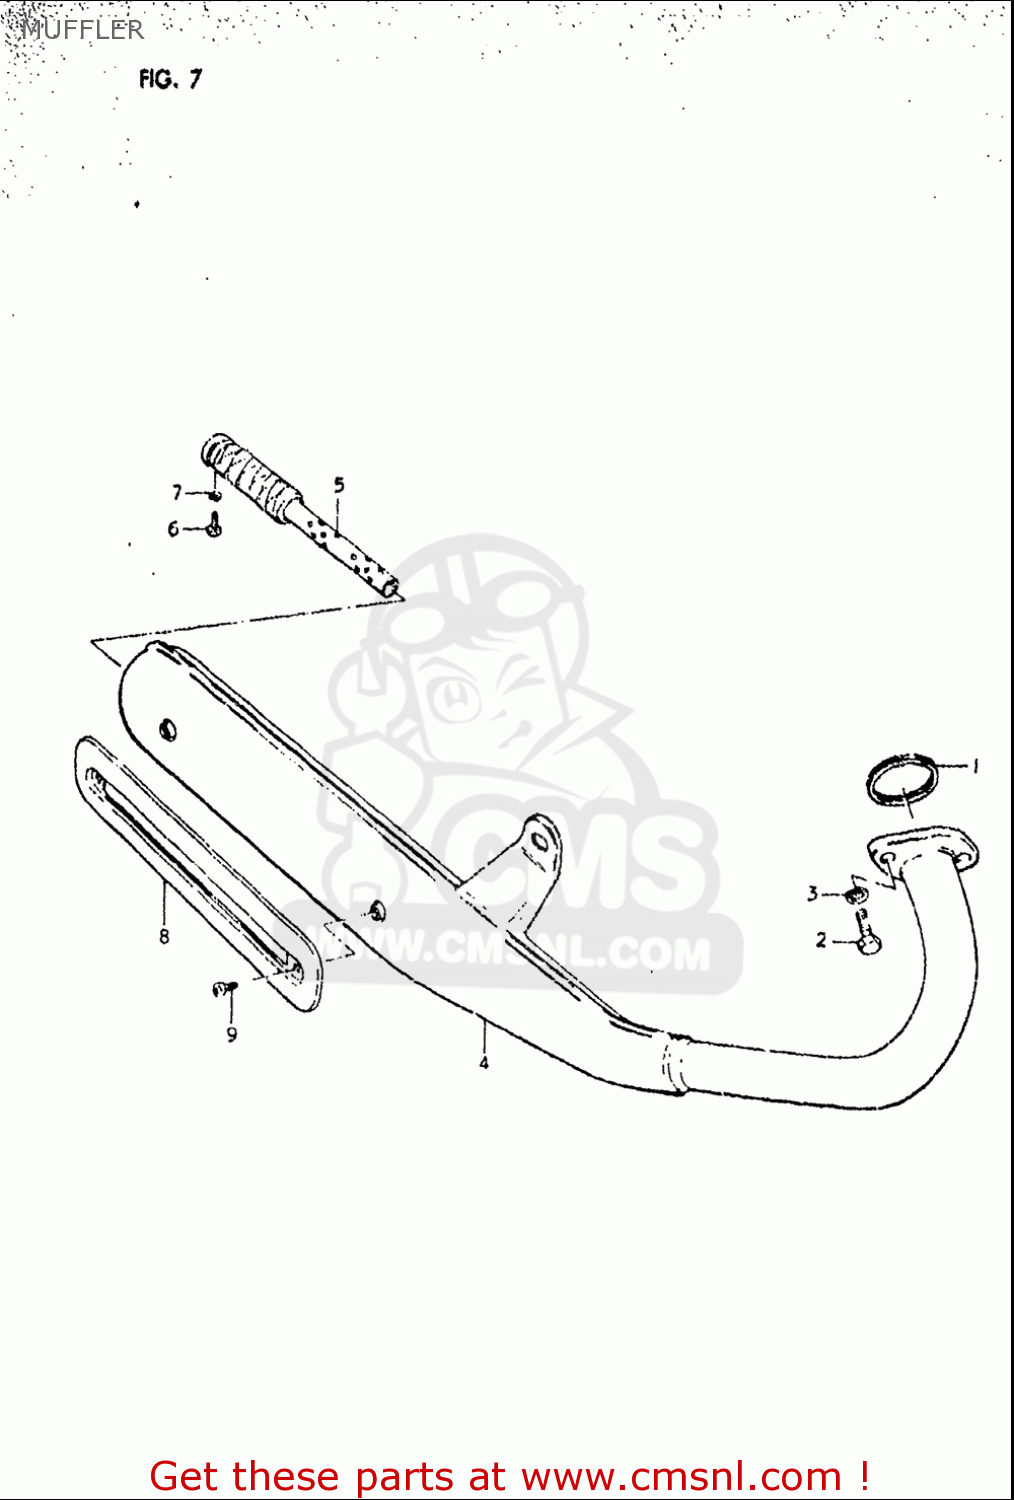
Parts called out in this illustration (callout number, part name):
1	GASKET,EXHAUST (NAS)
2	BOLT
3	WASHER,LOCK
6	BOLT(5X8)
7	WASHER,LOCK
9	SCREW
